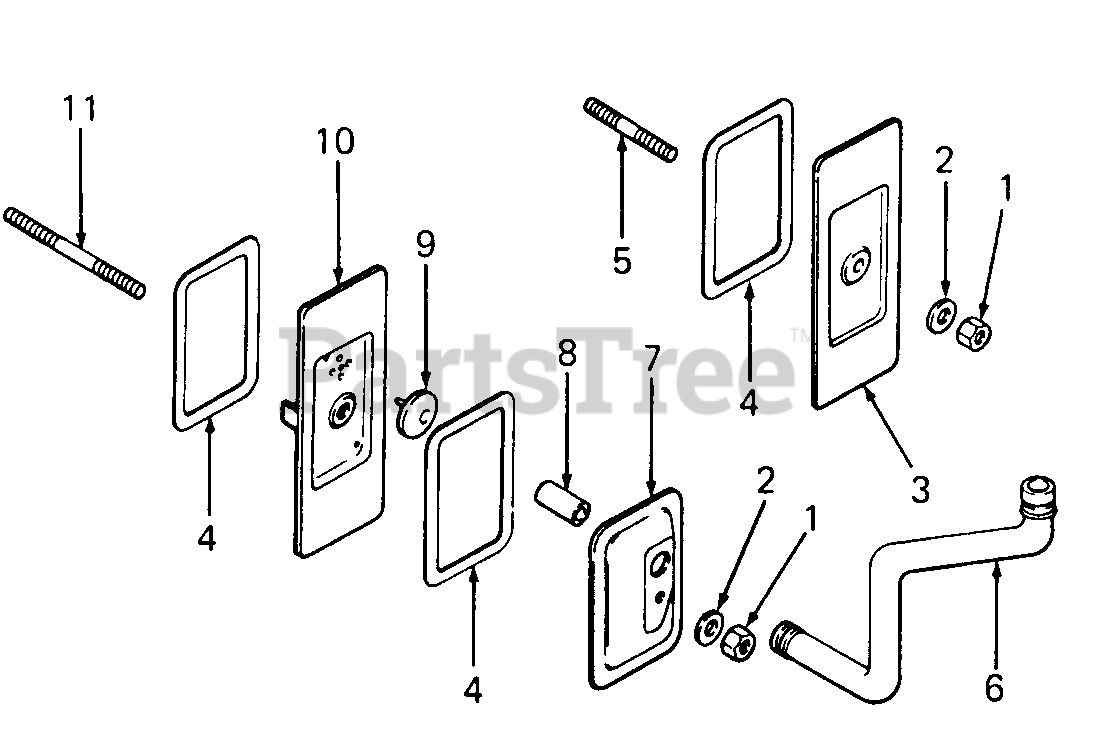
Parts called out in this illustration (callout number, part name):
1	Nut, Hex, 1/4-20
2	Washer, Plain, 1/4
3	Cover, #2 Cylinder Valve
4	Gasket, Valve Cover
5	Stud, #2 Cylinder Valve Cover, 1/4-20 X 2-1/4
6	Hose, Breather
7	Cover, #1 Upper Cylinder Valve
8	Seal, Breather
9	Valve, Umbrella
10	Cover, #1 Lower Cylinder Valve
11	Stud, #1 Cylinder Valve Cover, 1/4-20 X 3-1/4
